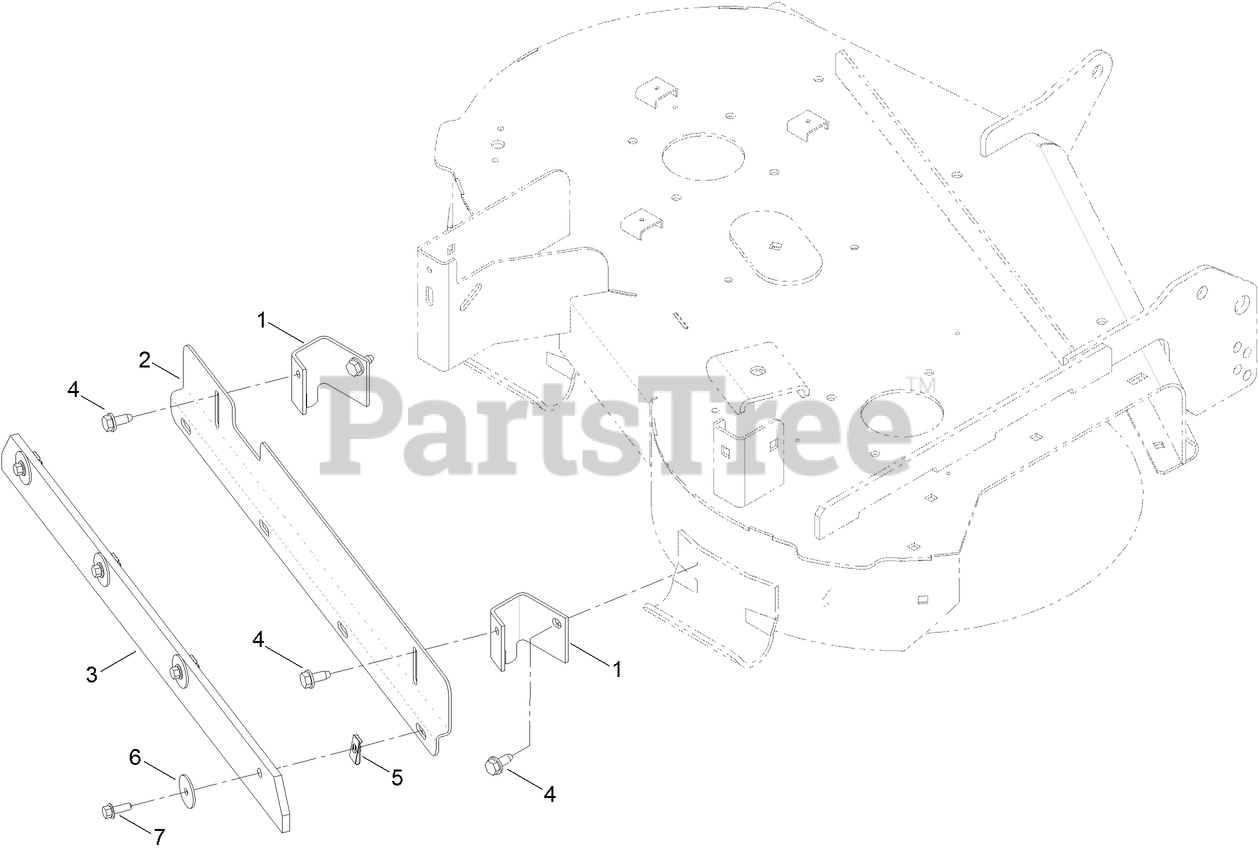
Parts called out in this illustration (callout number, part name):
2	BRACKET-STRIPING, 34" FAB
3	WIPER-34"
4	SCREW-HWHTF
5	NUT-SPEED
6	WASHER-FLAT
7	SCREW-HHF
